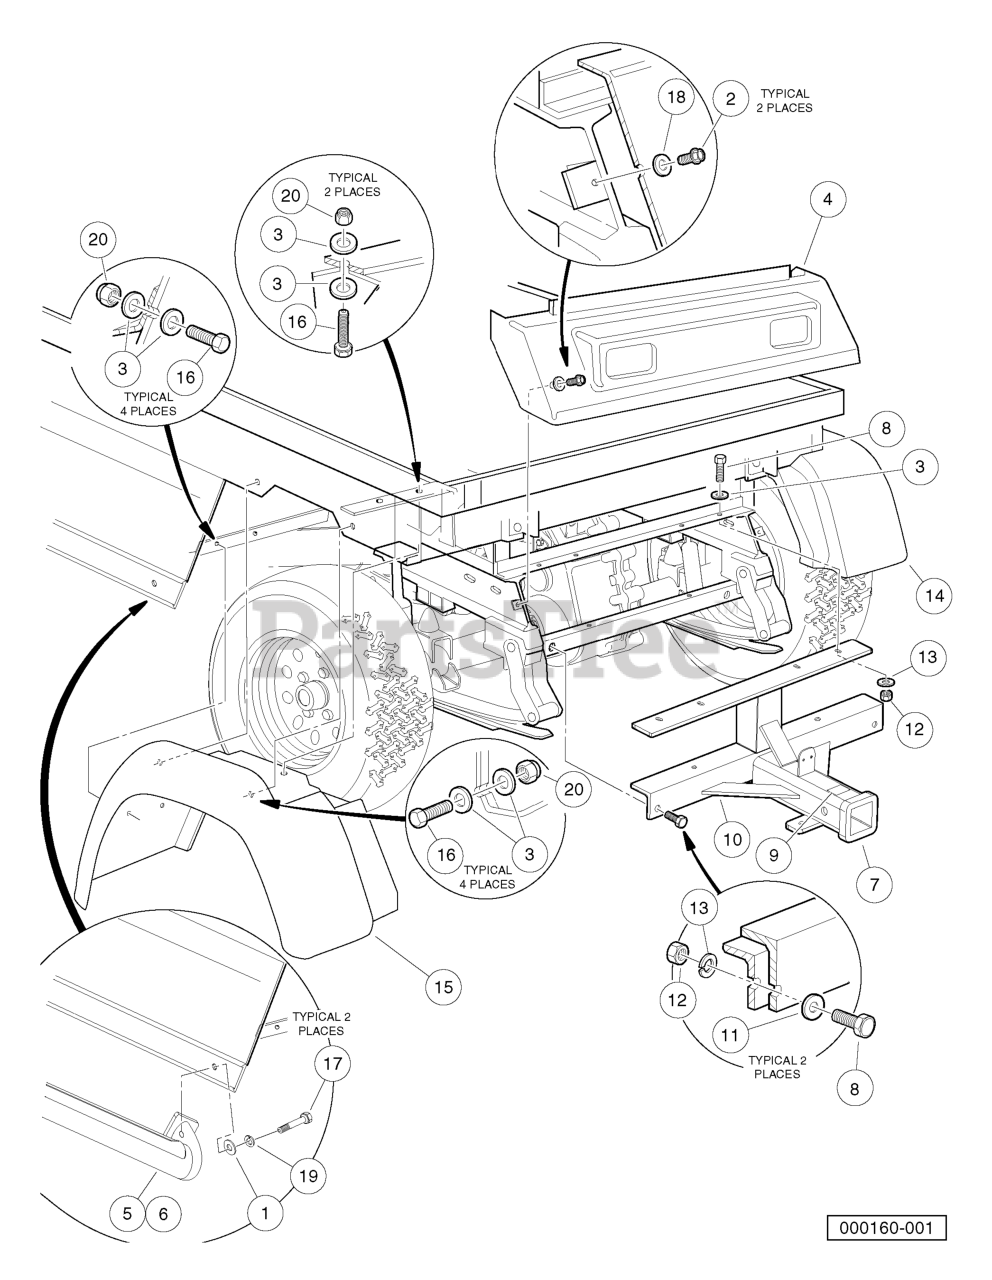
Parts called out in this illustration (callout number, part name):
1	WASHER, 3/8 FLAT
2	SCREW HX TYP TT
4	TAIL SKIRT, CAI
5	SIDE STEP BAR
6	SIDE STEP BAR
7	KIT, REAR RECEIVER
8	SCREW HEX CAP
9	DECAL, TRAILER HITCH
10	RECEIVER HITCH WELD ASM
11	WASHER, 5/16 TYPE A FLAT
12	NUT, 5/16-18 HEX
13	LOCKWASHER, 5/16 SPLIT
14	FENDER, RIGHT REAR
15	FENDER, LEFT REAR
17	SCREW, CAP, HEX HD 3/8-16X1.00
18	WASHER 1/4 FLAT
19	WASHER,LOCK,HEL SP 3/8 REG
20	LOCKNUT, 1/4-20 NYLON INSERT
